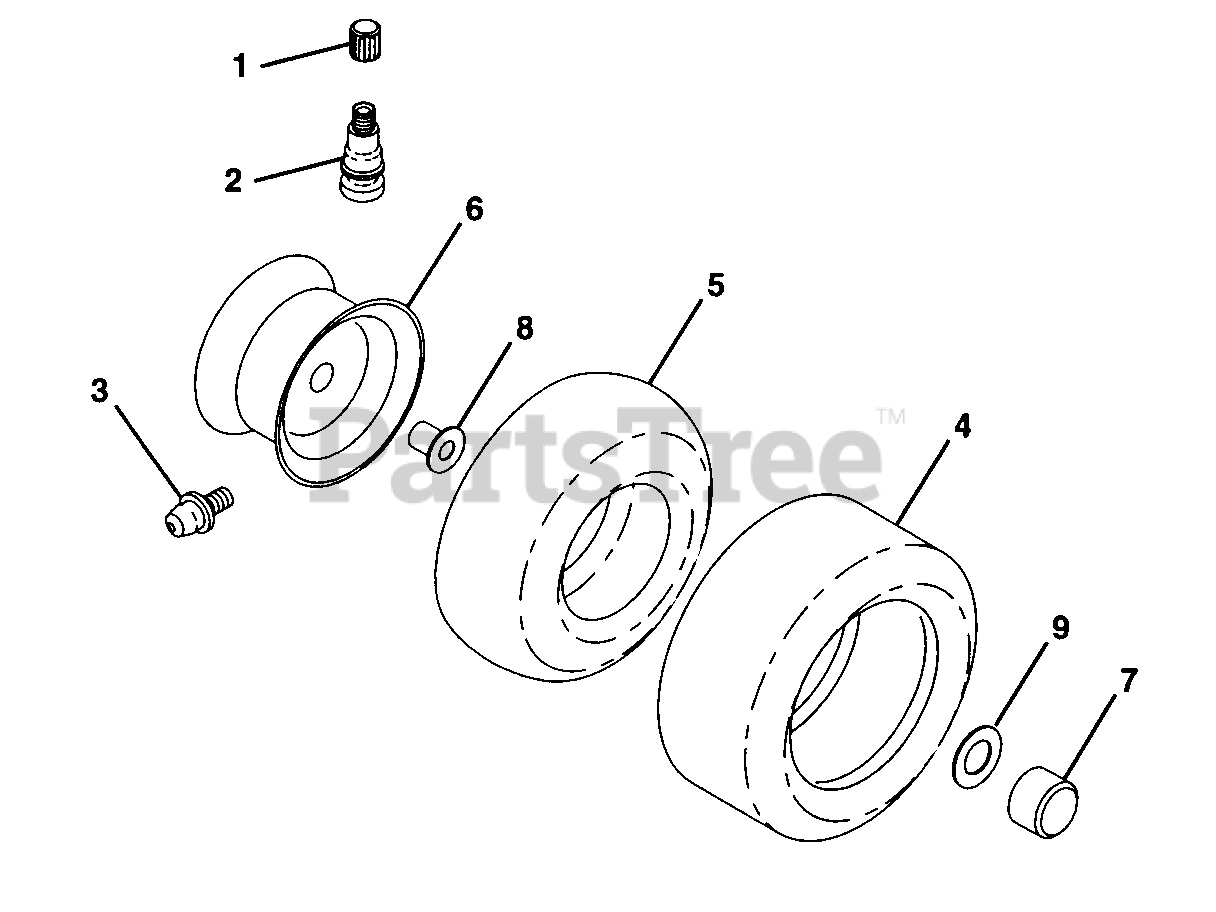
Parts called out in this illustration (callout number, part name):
1	Cap, Valve
2	Stem, Valve
3	Fitting, Grease
4	Tire, Front
4	Tire, Rear
5	Tube, Front
5	Tube, Rear
6	Rim, Front
8	Bearing Flange
9	Washer 25/32 x 1-5/8 x 16 Ga.
